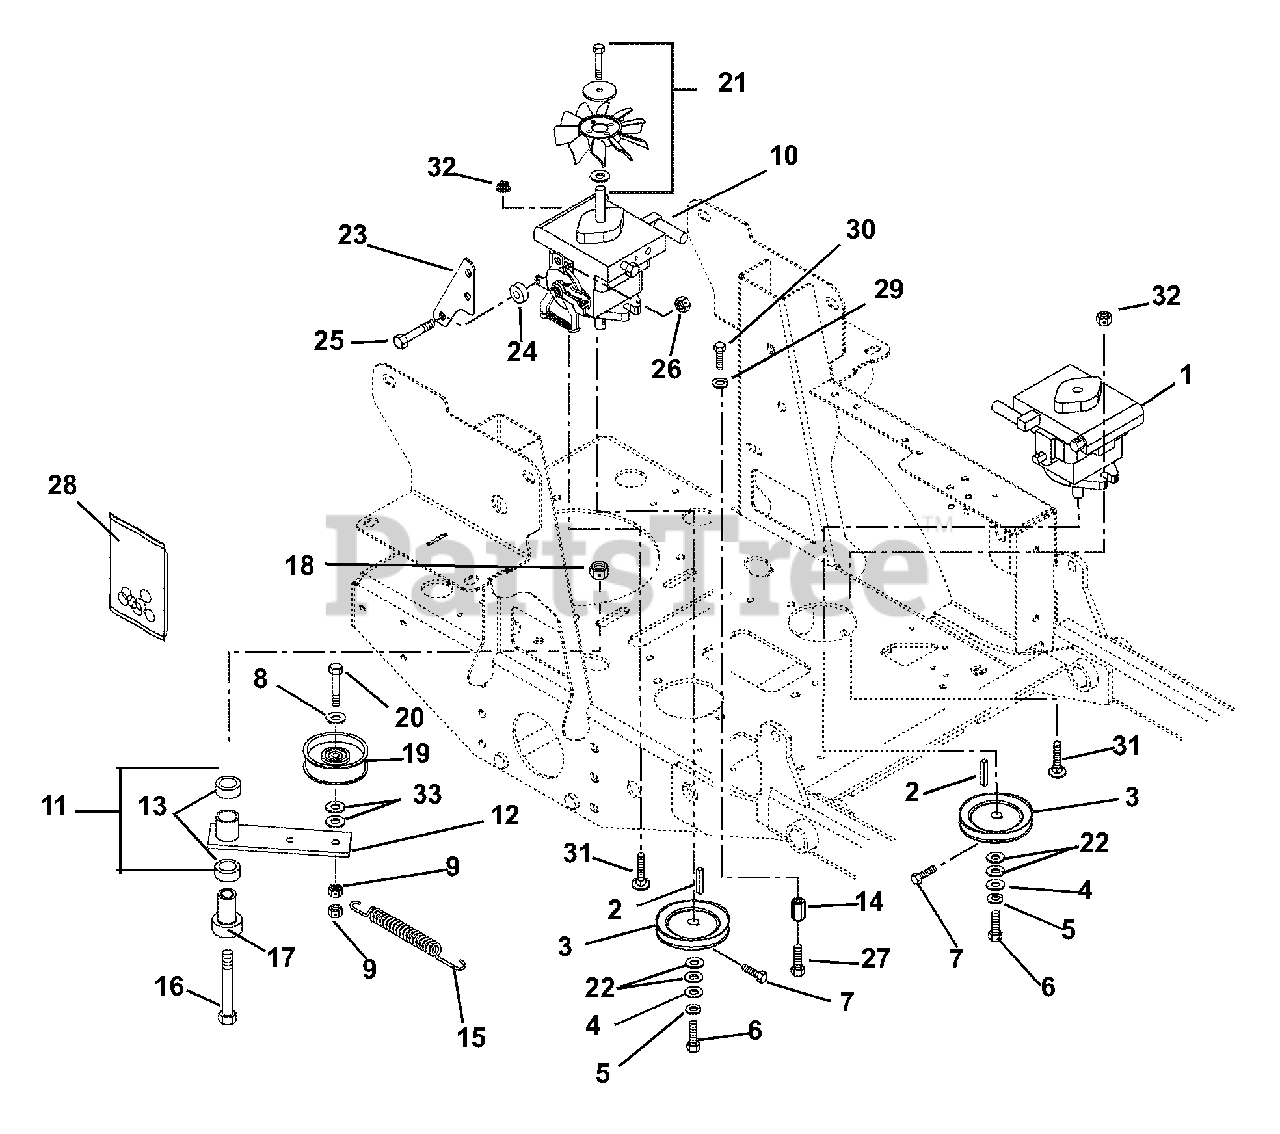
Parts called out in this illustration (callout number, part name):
1	Pump, Hydraulic BDP-10A Left Hand
2	Key, Straight 5mm x 25mm x 5mm
3	Sheave 4.0 x .199
4	Washer, Flat Steel .281 x 1.00 x .063
5	Washer, Locking .25 x .062
6	Bolt, Hex M6 x 1.00 x 12 Epoxy 30
7	Bolt, Hex .25-20 x .50 Grade 5
8	Washer, Flat Steel .406 x .812 x .065
9	Nut, Nyloc Flange .38-16
10	Pump, Hydraulic BDP-10A Right Hand
11	Assembly, Idler Arm Guard Drive
12	Weldment, Idler Arm Ground Drive
13	Bearing, 1.00 x 1.12 x .75
14	Nut, Coupling .375-16 x 1.75
15	Spring, Tension .120 x .845 x 6.50
16	Bolt, Hex .50-13 x 3.75 Grade 5
17	Bearing, Pedestal
18	Nut, Nyloc Flange .50-13
19	Idler, Flat 4.00 x 1.06 I.D.
20	Bolt, Hex .38-16 x 2.50 Grade 5
21	Fan, Cooling
22	Washer, Flat Steel .656 x 1.31 x .095
23	Bracket, Return to Neutral/Damper
24	Spacer .344 x 1.00 x .375
25	Bolt, Hex .31-18 x 1.25 Grade 5
26	Nut, Nyloc Flange .312-18
27	Bolt, Hex .38-16 x 1.50 Grade 5
28	Kit, Pump Seal (BDP-10A)
29	Washer, Locking .38 x .094
30	Bolt, Hex .38-16 x .75 Grade 5
31	Bolt-Round Head Square Neck .44-14 x 1.50 Grade 5
32	Nut, Nyloc Flange .44-14
33	Washer, Flat Steel .406 x 1.00 x .188
